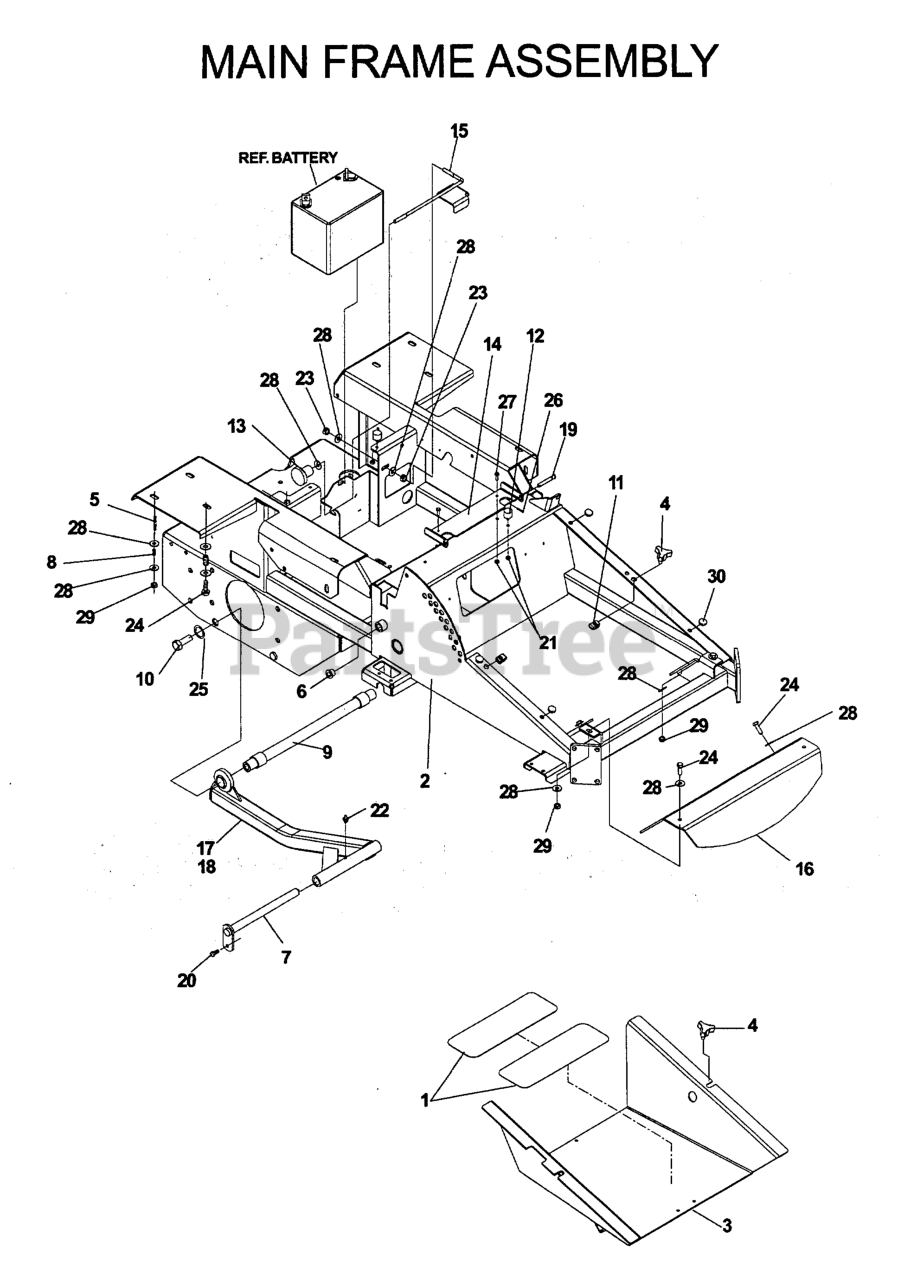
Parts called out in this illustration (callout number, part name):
1	ANTI-SKID PAD
2	IZ FRAME W/DECALS
3	IZ FOOTPLATE W/DECAL
4	KNOB W/STUD
5	STUD, 5/16C
9	STRUT MOUNT WELDMENT
10	HCS 5/8C X 2 GR.5
11	U-CLIP 5/16-18 NUT RETAINER
12	STUD/PLATE MOUNT
14	SEAT BRKT W/DECAL
15	BATTERY HOLD DOWN
16	FOOTREST ORANGE
19	CLEVIS PIN 3/8
20	HCS 5/16C X 3/4
21	NUT.1/4-20.HEX.NYLOC.ZD
22	ZERK
23	NUT 5/16C CENTERLOCK
24	HCS 5/16C X 1
25	LOCKWASHER 5/8
26	RP_COTTER PIN 1/8 X 3/4
27	HCS 1/4C X 3/4 HCS
28	WASHER 5/16 FLAT
29	NUT 5/16 NYLOC
30	GROMMET, BUMPER
